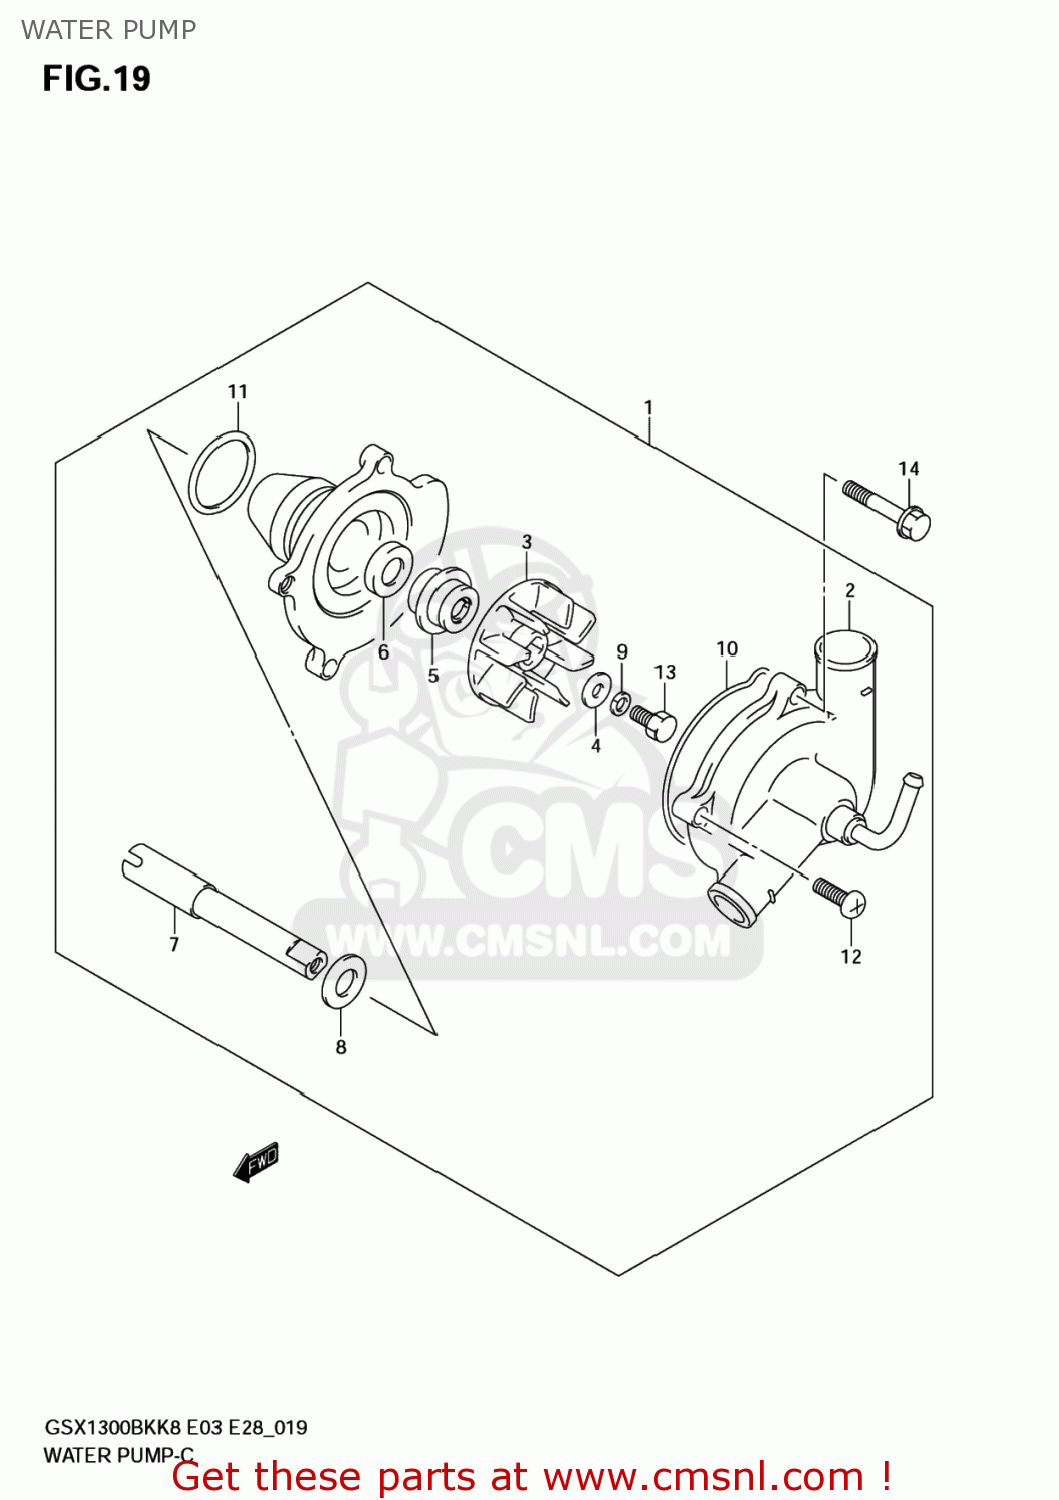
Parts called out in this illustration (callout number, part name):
1	PUMP ASSY,WATER
2	CASE,WATER PUMP
3	IMPELLER
4	GASKET(6X15X2.2) (NAS)
5	SEAL,MECHANICAL
6	SEAL,OIL
7	SHAFT
8	WASHER
9	WASHER
10	O RING
11	O RING,WATER PUMP HOLDER
12	SCREW
13	BOLT(6X13)
14	BOLT
